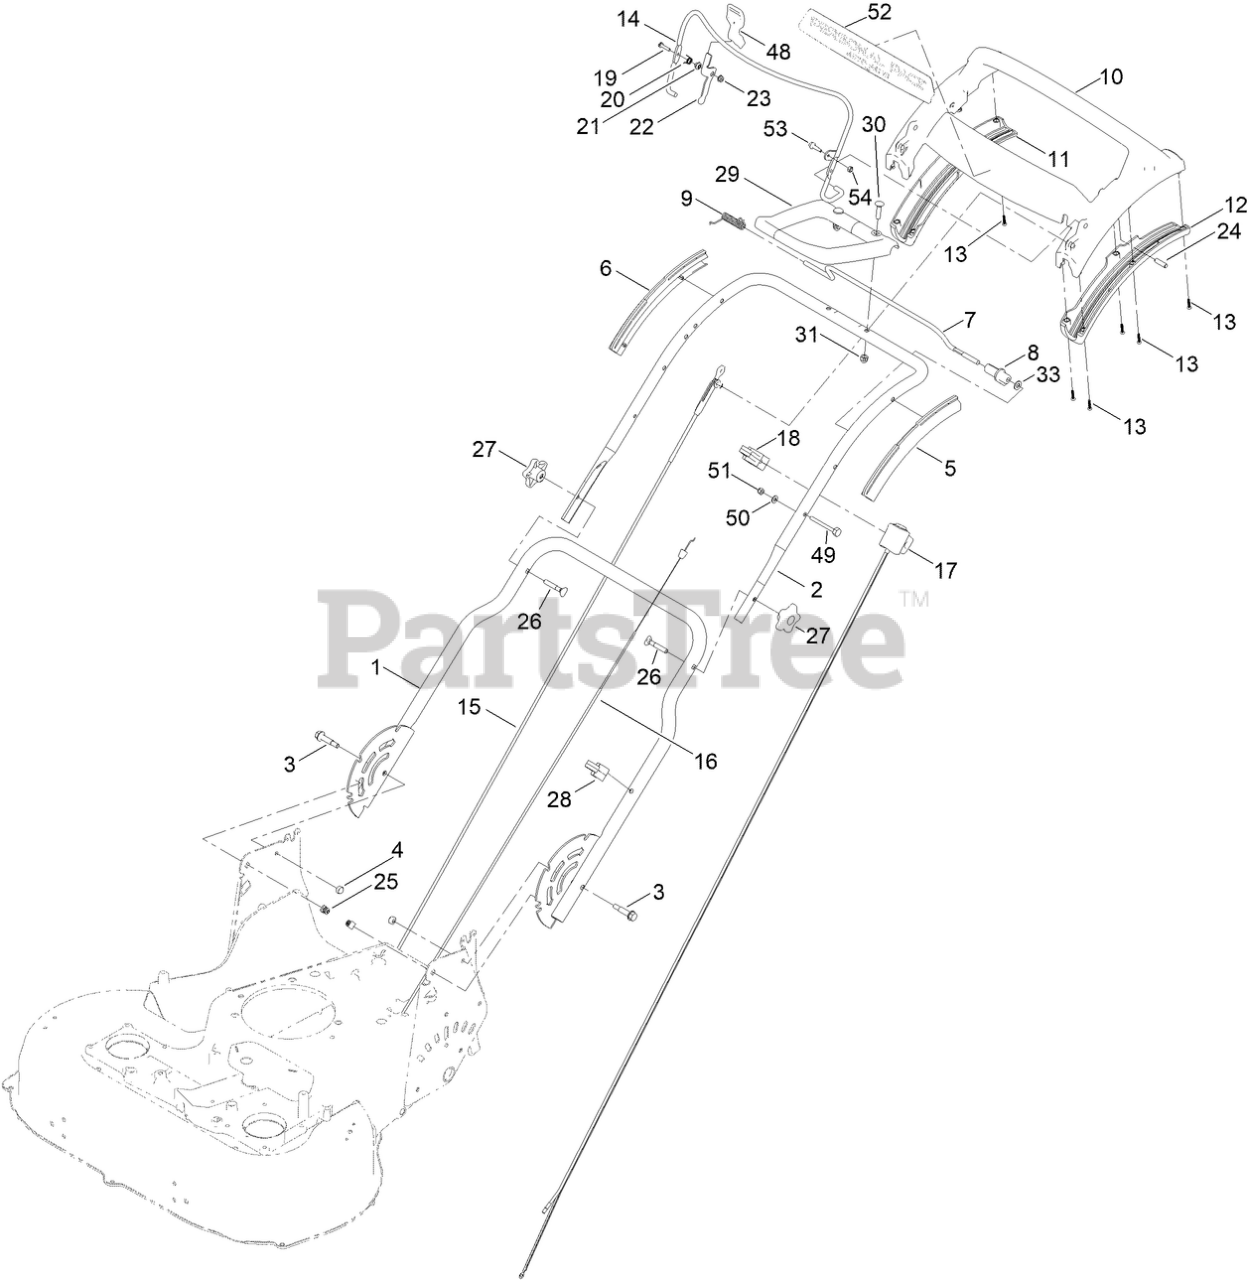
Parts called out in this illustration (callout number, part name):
1	HANDLE-LOWER, ASM
2	HANDLE-UPPER
3	BOLT-SHOULDER, HHF
4	NUT-LOCK, NI
5	GUIDE-CURVED, LH (RWD)
6	GUIDE-CURVED, RH (RWD)
7	ROD-CONTROL, TRACTION
8	LEVER-TRACTION, RWD
9	SPRING-TORSION
10	HANDLE-PERSONAL PACE, CURVED
11	BOTTOM-HANDLE, RH
12	BOTTOM-HANDLE, LH
13	SCREW-PPH
14	BAIL-BRAKE, BBC WELDED
15	CABLE-BRAKE
16	CABLE-TRACTION
17	SWITCH HOUSING ASM
18	ANCHOR-CABLE, RWD
19	SCREW-HWH
20	SPRING-TORSION
21	SPACER
23	NUT-LOCK, FLANGE
24	PIN-HANDLE, PP
25	PLUG-SQUARE
26	SCREW-HANDLE
27	KNOB-HANDLE
28	GUIDE-CABLE
29	HANDLE-ASSIST
30	BOLT-CARRIAGE
31	NUT-ACORN
33	WASHER-PLAIN
49	SCREW-HH
50	WASHER-FLAT
51	NUT-LOCK, NI
52	DECAL-HANDLE, PP
53	SCREW-SHOULDER
54	NUT-HEX
